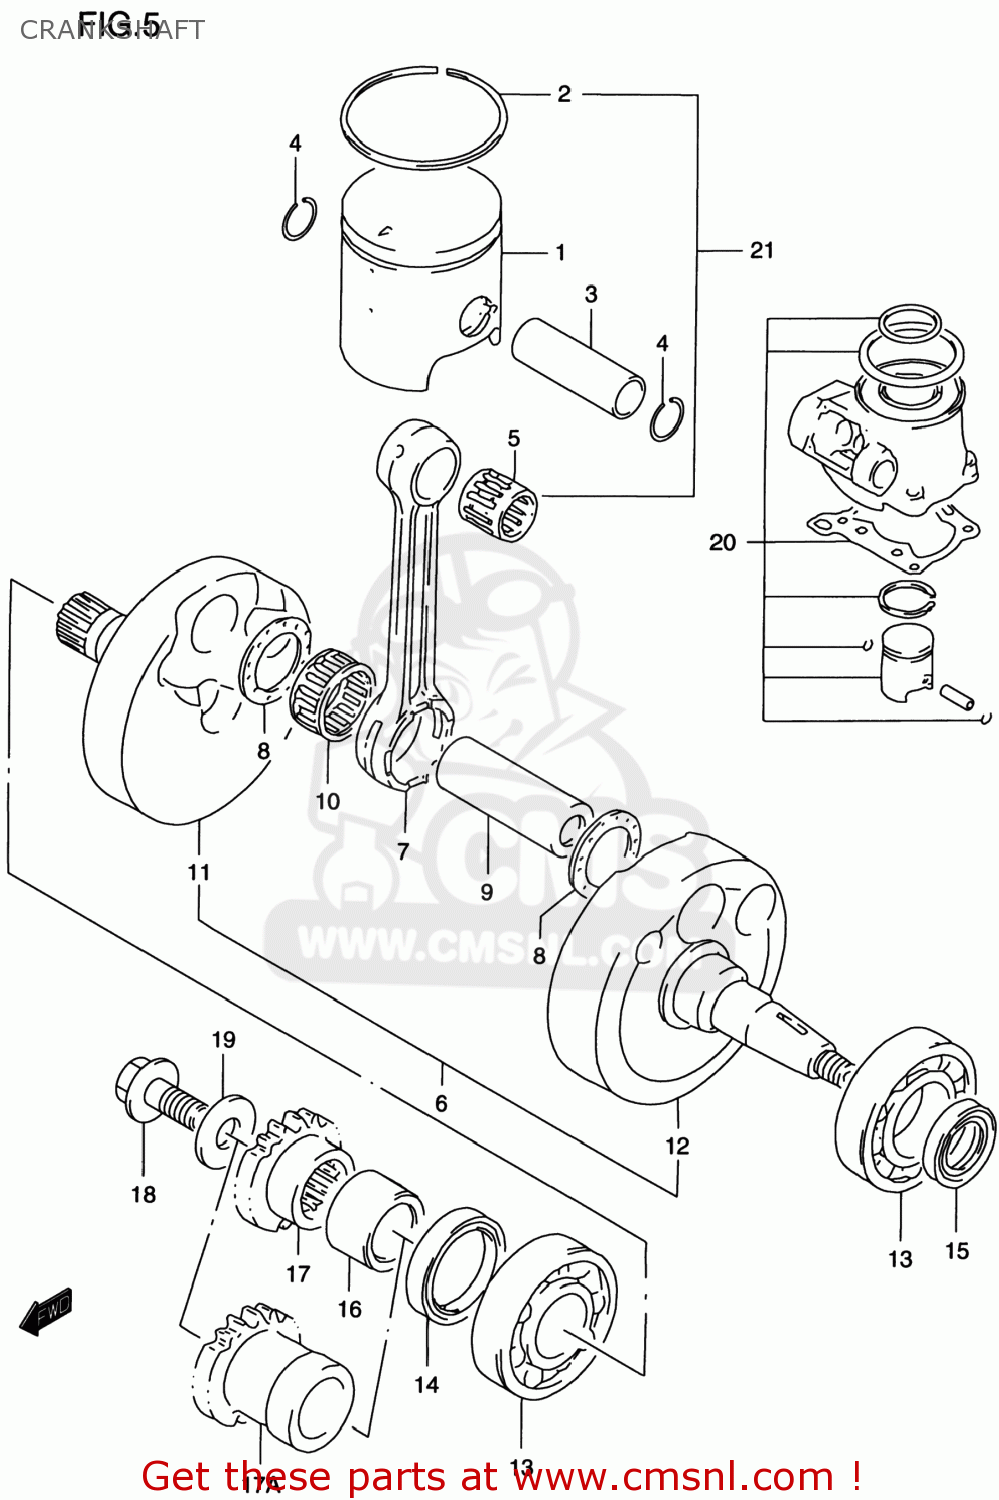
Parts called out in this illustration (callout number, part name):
1	PISTON
2	RING,PISTON
3	PIN,PISTON
4	CIRCLIP
5	BEARING(15X19X20)
6	CRANKSHAFT ASSY
7	CONNECTING ROD
8	WASHER(22X36X1.5)
9	PIN,CRANK
10	BEARING(22X28X16)
11	CRANKSHAFT,R
12	CRANKSHAFT,L
13	BEARING(22X56X16)
14	SEAL,OIL(30X40X7)
15	SEAL,OIL(18X30X6)
16	SPACER,PRIMARY DRIVE GEAR
17	GEAR,PRIMARY DRIVE (NT:
17A	GEAR,PRIMARY DRIVE
18	BOLT,PRIMARY DRIVE GEAR
19	WASHER
20	TOP END KIT,ENGINE
21	PISTON KIT
